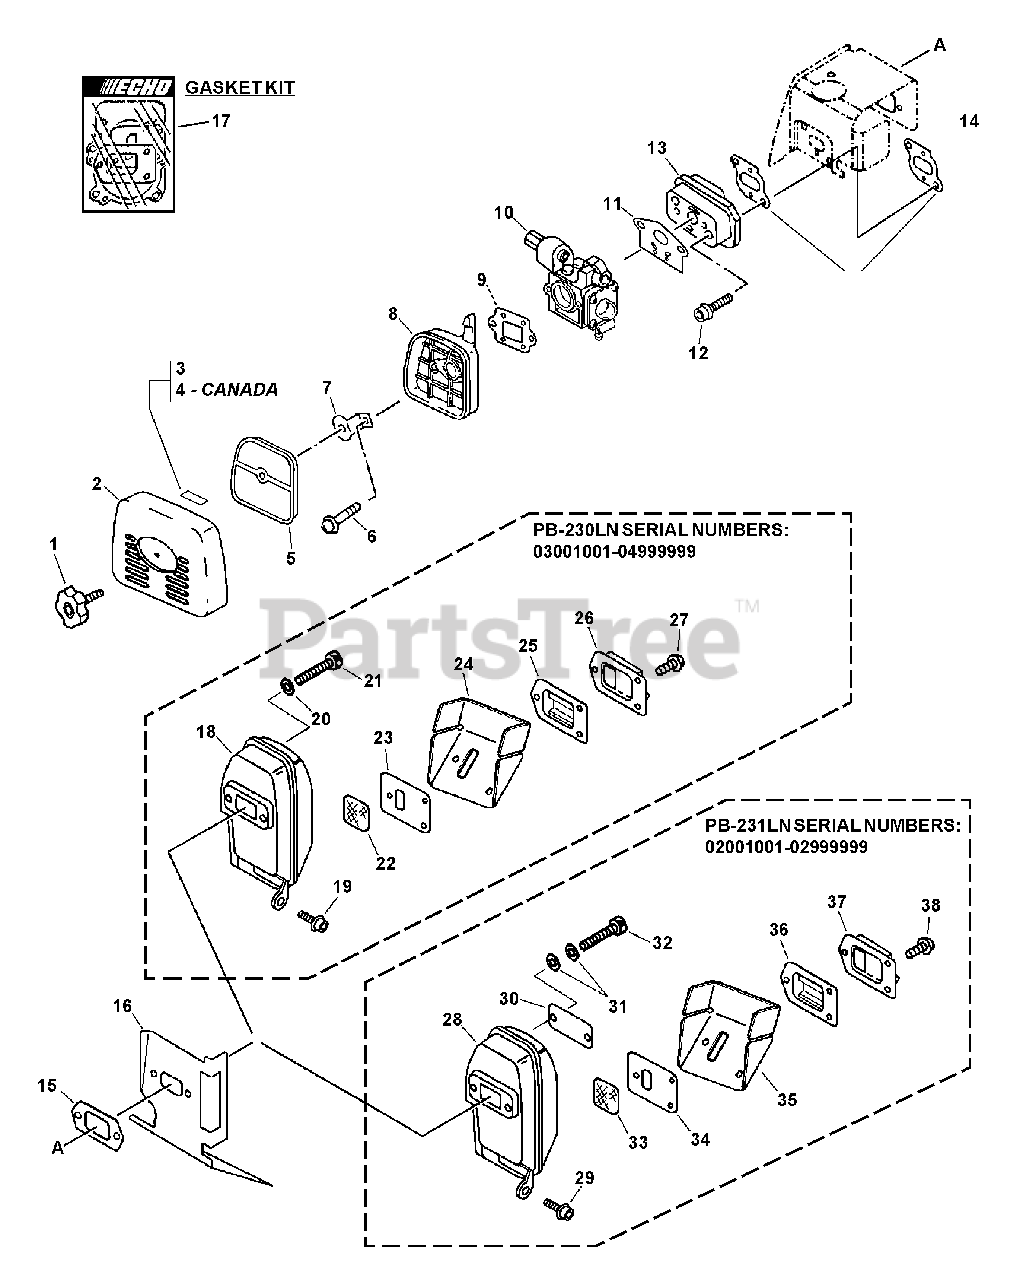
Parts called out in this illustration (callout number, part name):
1	THUMBSCREW
2	COVER, AIR FILTER
3	LABEL - CHOKE
4	LABEL - CHOKE
5	FILTER, AIR - HEAVY DUTY
6	SCREW - 5X60
7	PLATE, PREVENT
8	CASE, AIR FILTER
10	CARBURETOR RB-K60A
11	GASKET, INTAKE
12	SCREW - 5X25
13	INSULATOR, INTAKE
14	GASKET, INTAKE
15	GASKET, EXHAUST
16	SHIELD, EXHAUST
17	GASKET KIT
18	MUFFLER
19	SCREW - 5X16
20	WASHER - 5
21	SCREW - 5X60
22	SCREEN, SPARK ARRESTOR
23	GASKET, EXHAUST
24	GASKET, EXHAUST
25	GUIDE, EXHAUST - INNER
26	GUIDE, EXHAUST
27	SCREW - 4X12
28	MUFFLER
29	SCREW - 5X16
30	PLATE
31	WASHER - CONICAL
32	BOLT - 5X65
33	SCREEN, SPARK ARRESTOR
34	GASKET, EXHAUST
35	GASKET, EXHAUST
36	GUIDE, EXHAUST - INNER
37	GUIDE, EXHAUST
38	SCREW - 4X12
